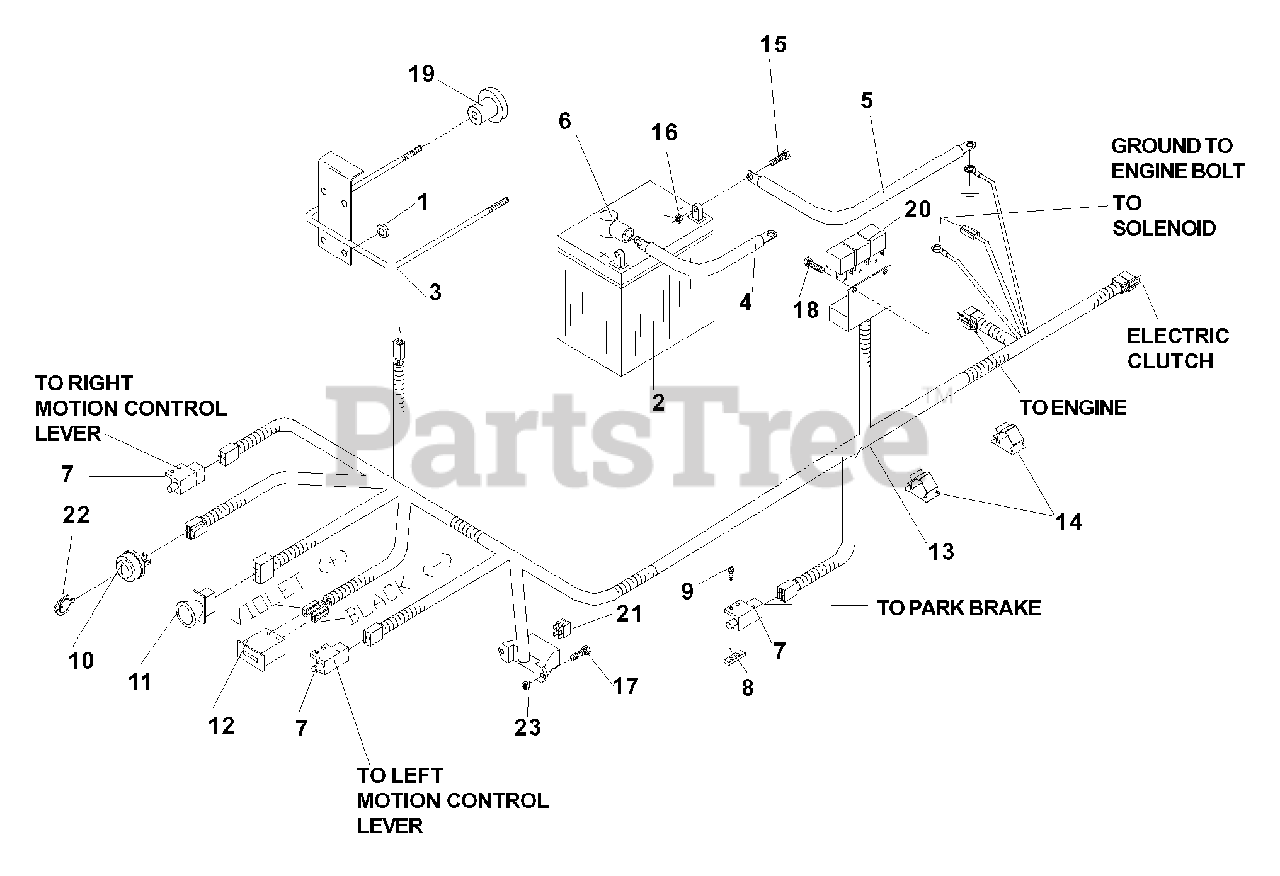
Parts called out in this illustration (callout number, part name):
2	BATTERY, DRY
3	BATTERY HOLD DOWN
4	CABLE, POSITIVE, LONG
5	CABLE, NEGATIVE
7	SWITCH, INTERLOCK
8	PLATE, TAPPED
9	SCREW, #10-24 x 5/8
10	SWITCH, IGNITION
11	SWITCH, BLADE
12	METER, HOUR
13	HARNESS, FRAME
14	PUSH MOUNT, WIRE CLIP
15	HCS, 5/16C x 3/4
16	NUT, 5/16C, NYLOC
17	SCREW, #10-24 x 7/8
18	SCREW, SELF TAPPING
21	FUSE, 7.5 AMP 32V ATO
22	KEY, IGNITION, PADDED
23	NUT, #10-24, NYLOC
